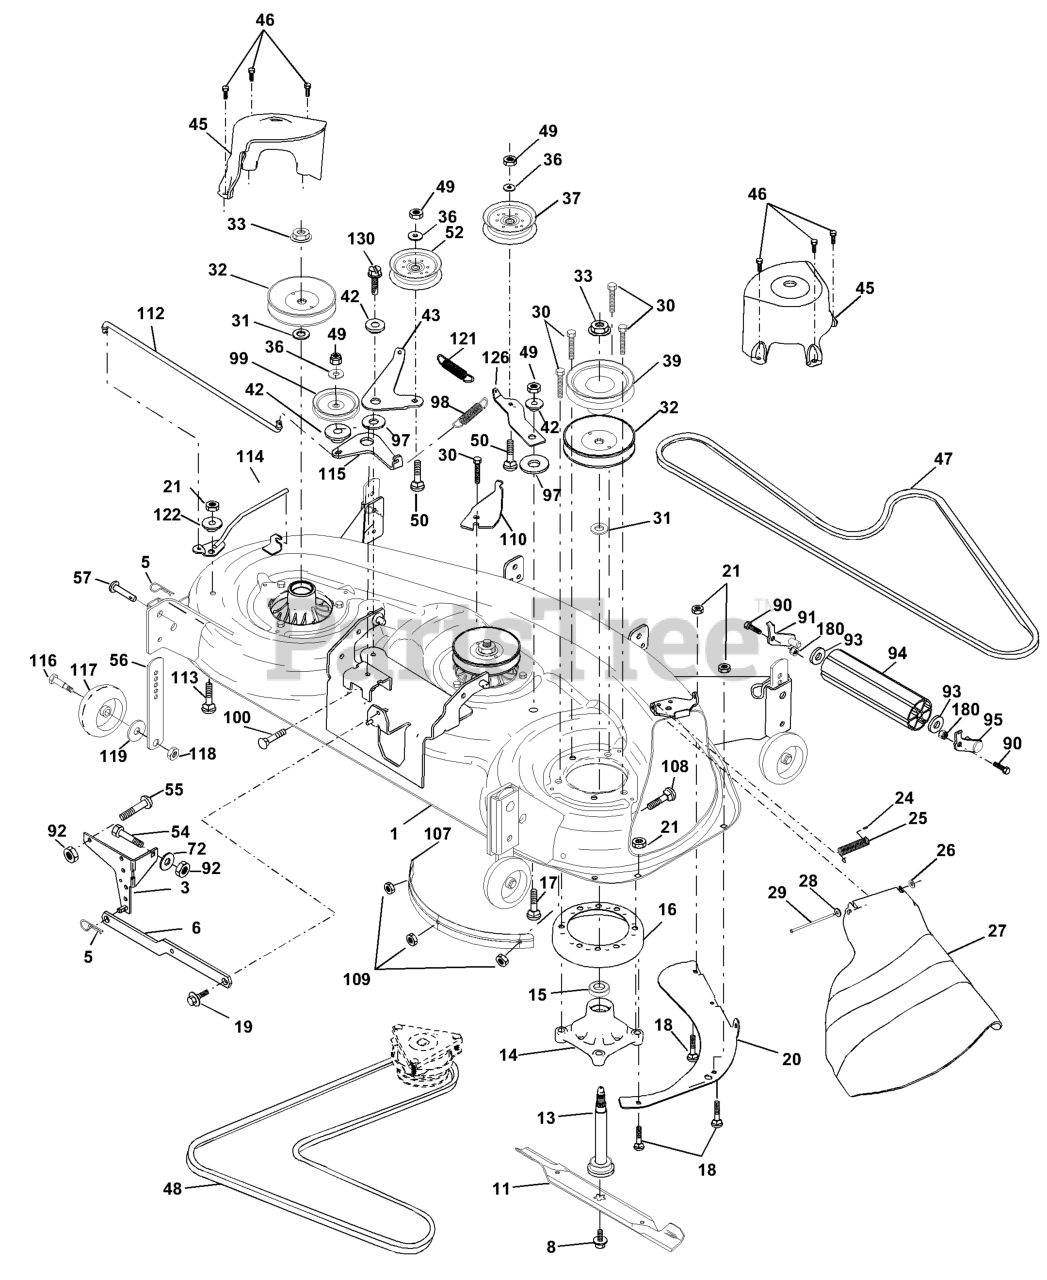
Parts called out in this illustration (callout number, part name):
1	DECK, WELDMENT MWR 48"
3	BRKT ASM SWAY BAR
5	RETAINER SPRING
6	REAR SUSP ARM
8	BOLT 7/16 ASM BLADE
10	WASHER.BLADE
11	BLADE
13	SHAFT ASM W/LOWER BEARING
14	HOUSING, MANDREL 48"
16	STRIPPER.MANDREL.ROUND.BLACK
17	BOLT
18	BOLT
19	BOLT SHD 5/16-18
20	BAFFLE, VORTEX MWR
21	LOCKNUT
24	CAP-SLEEVE LT
25	SPRING, TORSION
26	NUT PUSH M
27	SHIELD, DEFL. MWR
28	Washer 11/32 x 5/8 x 16 Ga.
29	ROD.HINGE
30	SCREW THDROL ROLLING WASHER HD
31	WASHER
32	PULLEY, MANDREL
33	NUT, FLG TOPLOCK 9/16"
36	WASHER
37	PULLEY.IDLER.FLAT.PLATED
38	REPL BY 532 1560-86
39	PULLEY.DRIVEN.DECK.48'
42	SPACER RETAINER
43	ARM, IDLER SECONDARY
45	COVER, MANDREL DECK
46	SCREW.1/4-20X5/8
47	V-BELT, MWR SECONDARY
48	V-BELT PRIMARY 48"
50	BOLT.3/8-16X1.50
52	PULLEY.IDLER.FLAT.46.PR.DR.
54	BOLT
55	BOLT D
56	BAR.ADJUST.WHEEL.ANTI.SCALP.BL
57	RIVET.PIN.HEAD.YELLOW.
72	WASHER
90	BOLT RB
91	BRKT, ASM NOSEROLLER(R)48
92	NUT
93	Washer 17/32 x 7/8 x 16 Ga.
94	NOSE ROLLER 48"
95	BRKT ASM NOSEROLLER(L)48"
97	HARDENED WASHER
98	SPRING, PR. DRIVE
99	PULLEY,IDLER"V"
100	BOLT
107	BAFFLE.VAC.EDGE.MOWER.48"
109	Nut Crownlock 1/4-20
110	ARM, SPRING SECONDARY
112	LEVER, TENSION RELIEF LINK
113	BOLT CRT
114	LEVER ASM, TENSION RELIEF
115	ARM, SPRING TENSION RELIEF
116	BOLT, SHOULDER
117	WHEEL GAGE DONUT
118	LOCKNUT
119	WASHER.5/16.FLAT.STE.STD.
126	ARM, IDLER PRIMARY DECK
130	SCREW THDROL 3/8-16 X 1-1/2
180	NUT.71038.31-18.HEX.NYLOCK
